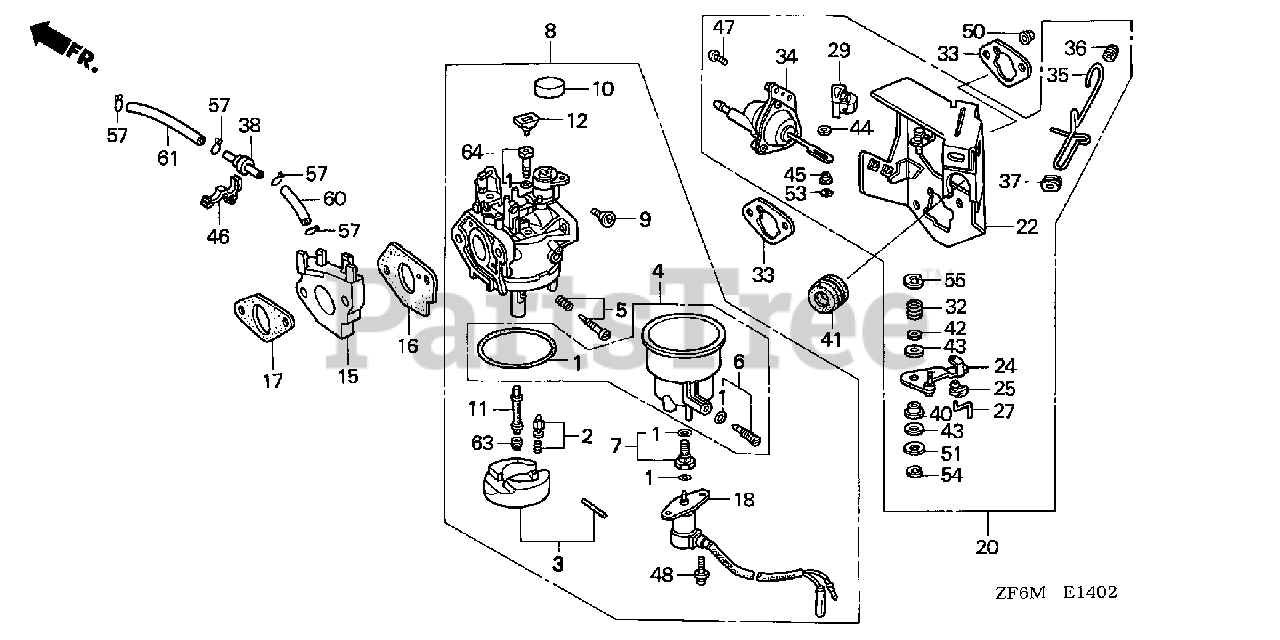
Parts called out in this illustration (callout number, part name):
1	GASKET SET
2	VALVE SET, FLOAT
3	FLOAT SET
4	CHAMBER SET, FLOAT
5	SCREW SET
6	SCREW SET, DRAIN
7	SCREW SET B
8	CARBURETOR ASSY. (BE87A A)
9	SCREW, THROTTLE STOP
10	CAP, CHOKE LEVER DUST
11	NOZZLE, MAIN
12	COLLAR, SET
15	INSULATOR, CARBURETOR
16	GASKET, CARBURETOR
17	GASKET, INSULATOR
18	VALVE ASSY., SOLENOID
20	STAY ASSY., MANUAL CHOKE
22	STAY, SOLENOID
24	LEVER, CHOKE
25	JOINT, ROD
27	ROD, CHOKE
29	STOPPER, CHOKE ROD
32	SPRING, MANUAL CHOKE
33	GASKET, AIR CLEANER
34	DIAPHRAGM ASSY.
35	ROD, CHOKE CONTROL
36	GROMMET, CHOKE ROD
37	GUIDE, CHOKE ROD
38	VALVE, DASHPOT CHECK
40	BUSH, ARM PIVOT
41	GROMMET, FENDER
42	WASHER, CHOKE LEVER
43	SEAL, CHOKE LEVER
44	WASHER, THRUST (2.7X8)
45	COLLAR, LEVER
46	CLIP, WIRE HARNESS
47	SCREW, PAN (5X12)
48	SCREW-WASHER (5X12)
50	NUT, FLANGE (6MM)
51	WASHER, PLAIN (5MM)
53	E-RING (2MM)
54	E-RING (4MM)
55	E-RING (7MM)
57	CLIP, TUBE (B7)
60	BULK HOSE, VACUUM (3.5X8000) (3.5X75)
61	BULK HOSE, VACUUM (3.5X8000) (3.5X130)
63	JET, MAIN (#98)
63	JET, MAIN (#100)
63	JET, MAIN (#102)
64	JET SET, PILOT (#45)
